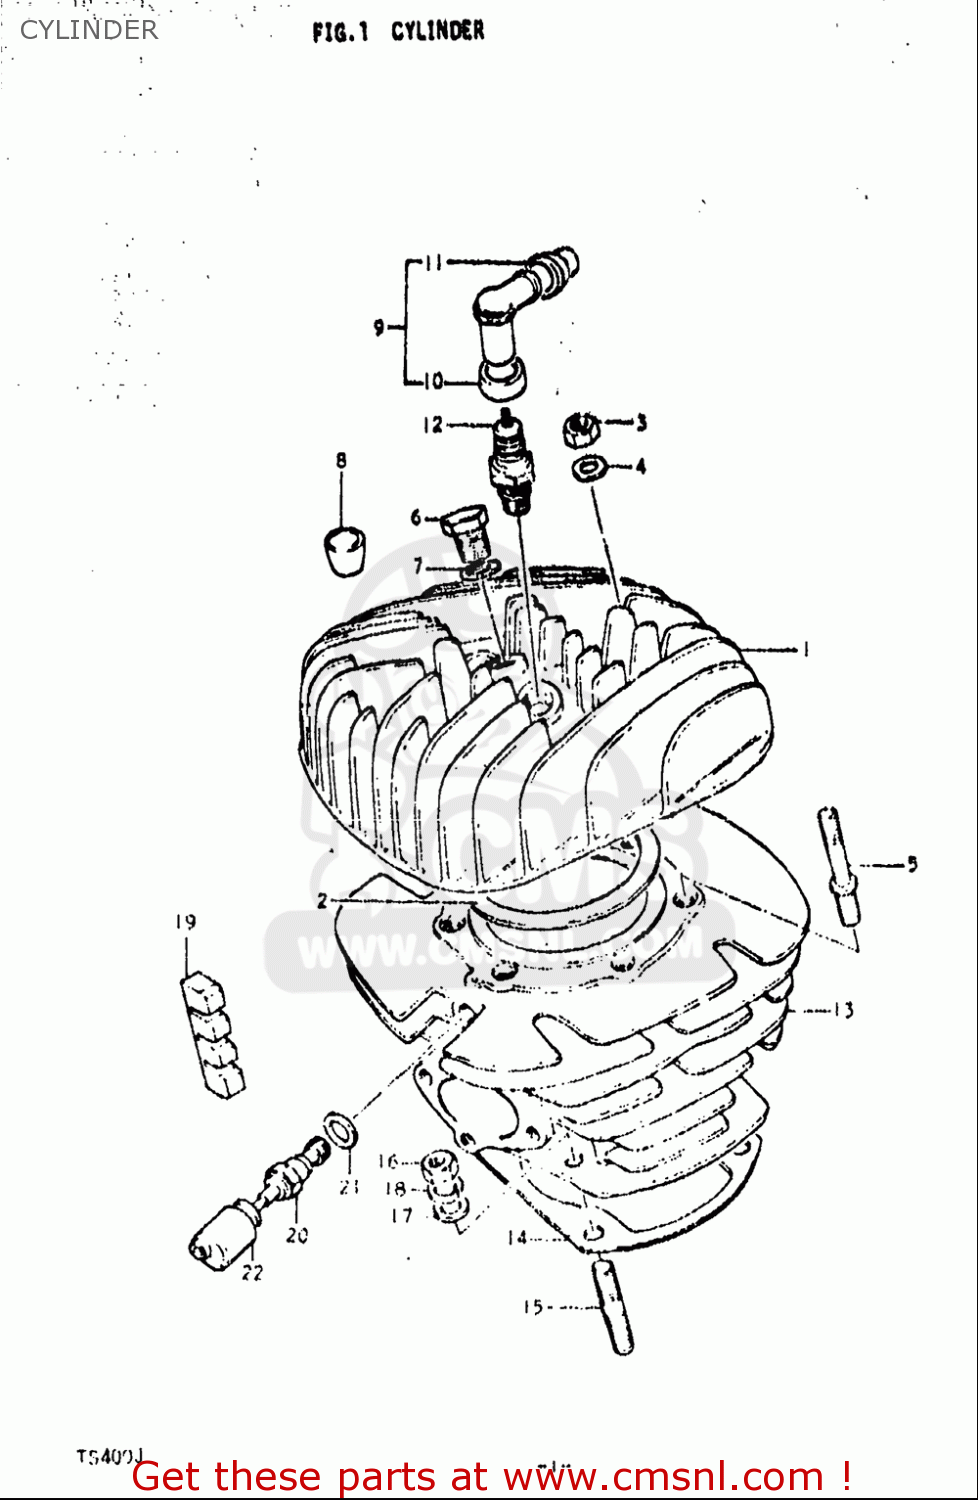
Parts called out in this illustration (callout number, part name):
2	GASKET,CYLINDER HEAD (NAS)
3	NUT
4	WASHER
5	BOLT,STUD
6	PLUG
7	GASKET(14X19.2X2) (NAS)
9	CAP,SPARK PLUG
10	SEAL,SPARK PLUG
11	SEAL,HIGH TENSION CORD
12	PLUG,SPARK
14	GASKET,CYLINDER (MCA)
15	STUD BOLT
16	NUT
17	WASHER
18	WASHER,LOCK
21	GASKET(12X16X2) (NAS)
